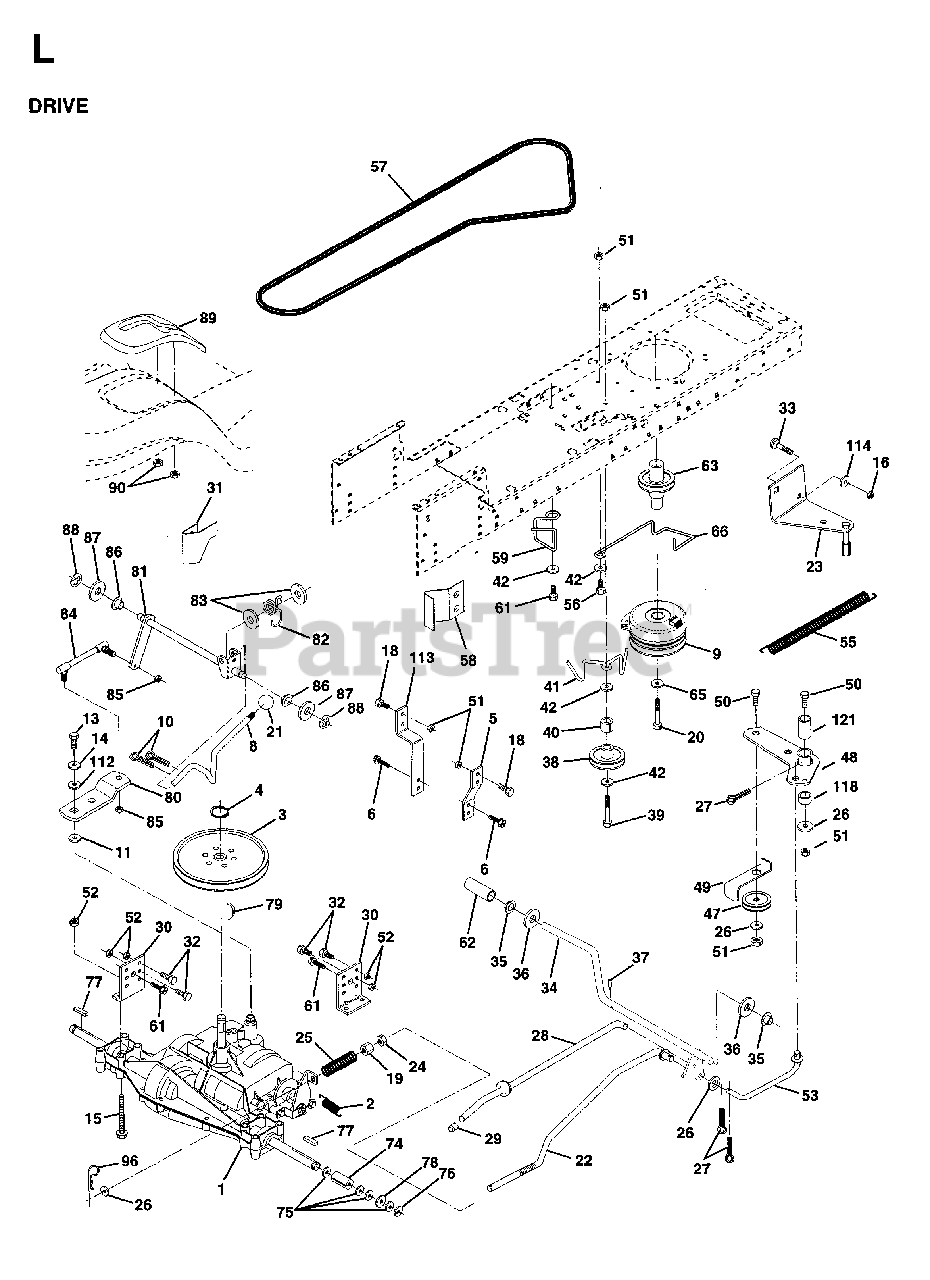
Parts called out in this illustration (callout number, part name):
2	SPRING,BRAKE RETURN
3	PULLEY TRANS
4	RETAINING RING LT
5	STRAP TORQUE
6	SCREW
8	ROD SHIFT FENDER
9	CLUTCH, ELECTRIC
10	PIN COTTER
11	WASH-SHFT PLT LT
13	BOLT 1/4-28X3/4
14	LOCKWASHER
15	BOLT HEX 5/16-18 GR 5
16	NUT.71038.31-18.HEX.NYLOCK
20	BOLT HEX
21	PISTOL KNOB
22	ROD BRAKE
24	NUT
25	SPRING ROD LT
27	COTTER PIN
28	ROD BRAKE PARK LT
29	PLUNGER CAP
30	BRACKET TRANSAXLE
31	KEEPER BELT LH
32	BOLT
33	BOLT
34	SHAFT, FOOT PEDAL
35	BEARING.NYLON
36	WASHER LT
37	DRIVE PIN
38	PULLEY.IDLER.FLAT
41	KEEPER, BELT IDLER
42	WASHER
47	IDLER PULLEY
48	BELLCRANK ASSEMBLY
49	RETAIN BELT
50	BOLT
51	LOCKNUT
52	LOCKNUT
53	LINK, CLUTCH LT
55	SPRING, RETURN LT
59	KEEPER CENTER SPAN
61	SCREW
62	PEDAL COVER T
63	PULLEY, CLUTCH ELECT EVX
65	LOCKWASHER
66	KEEPER BELT ENGINE
74	SPACER AXLE
76	E-RING LT
77	SQUARE KEY
80	ARM SHIFT
81	SHAFT ASM CROSS 20"
82	SPRING,TORSION
83	WASHER
84	ROD TIE 20"
85	NUT LOCK CENTER 1/4 -28 FNTHD
86	BUSHING.STEERING.ROD
88	KLIP RING
89	CONSOLE SHIFT
96	RETAINER M
112	WASHER LT
113	STRAP TORQUE LH LT
118	SPACER BELLCRANK
121	NYLINER CLUTCHING
